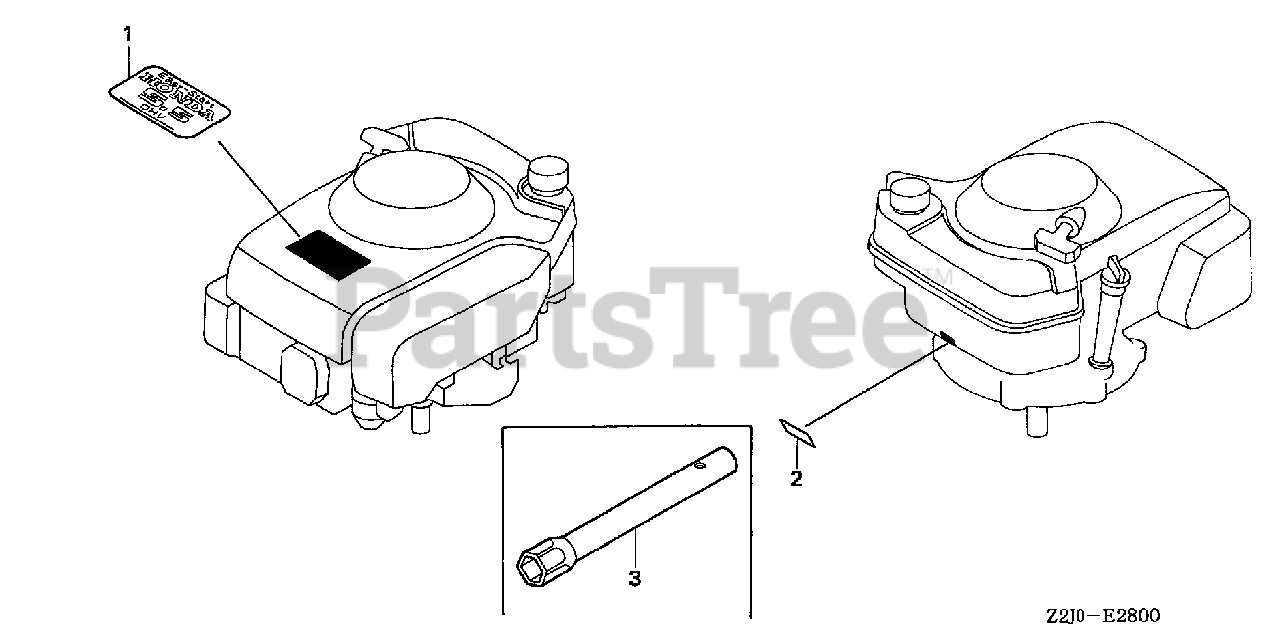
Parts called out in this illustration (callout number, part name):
1	EMBLEM (5.5)
2	MARK, TYPE (N12)
3	WRENCH, BOX (P21)
